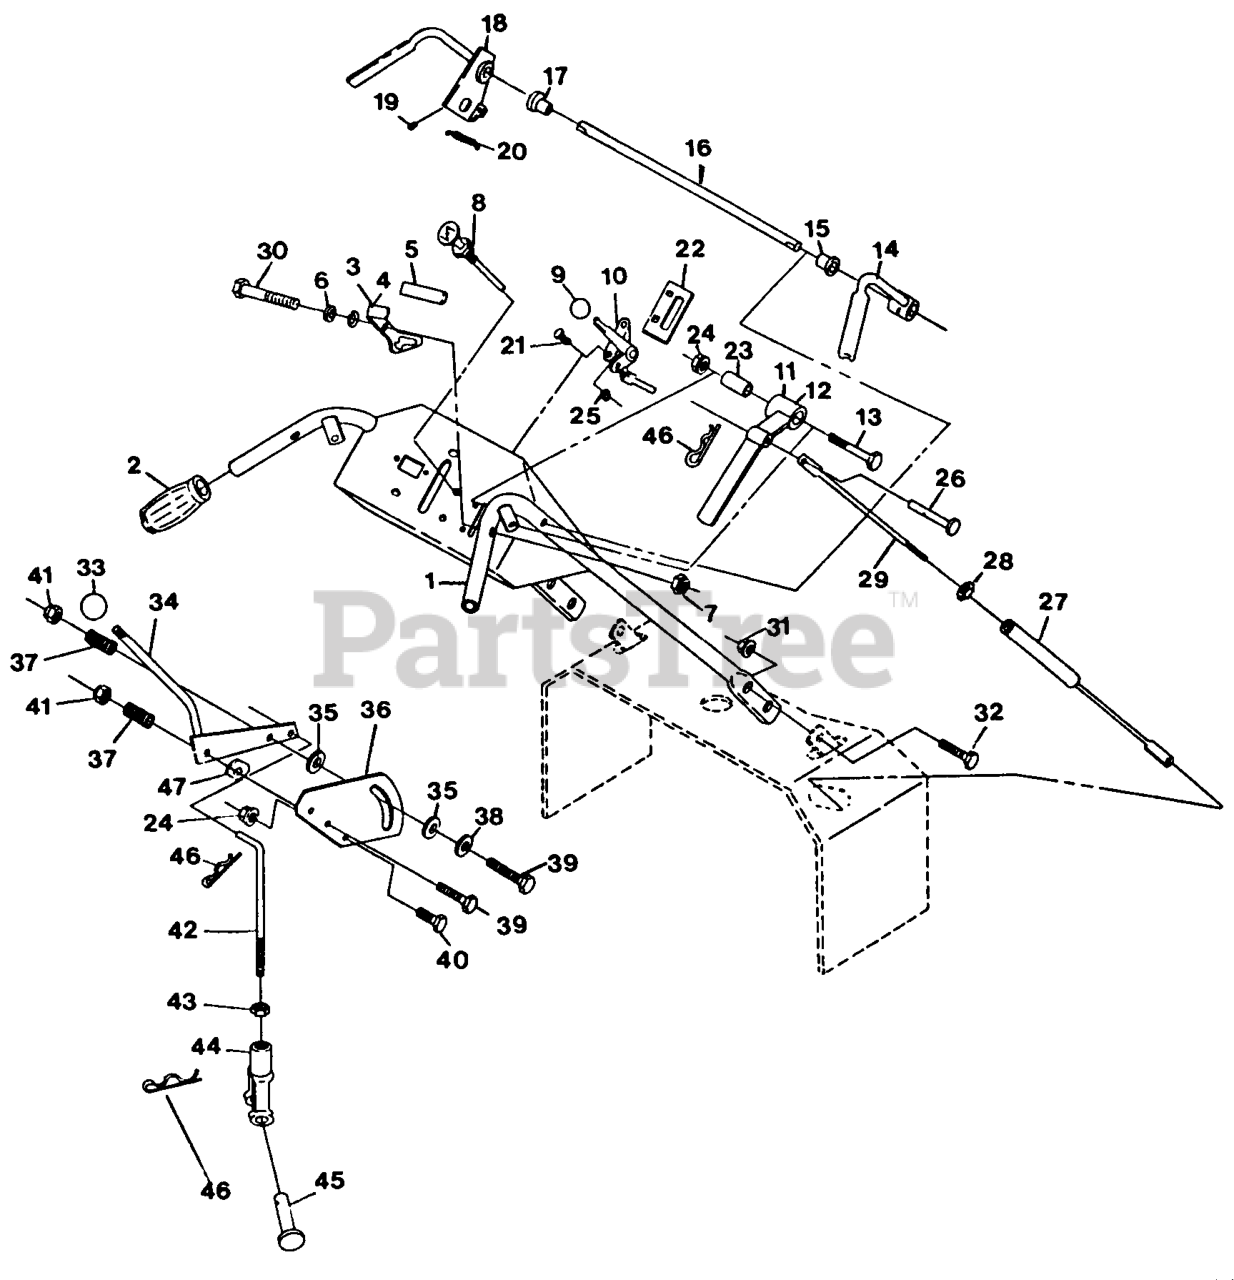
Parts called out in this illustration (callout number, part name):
5	GRIP-LATCH
6	WASHER-SPRING
8	CONTROL-CHOKE
9	KNOB-BALL
15	BUSHING-NYLON
16	ROD,CONNECTING
17	BUSHING,FLANGED
19	SCREW-SET
20	SPRING-EXTENSION
21	BOLT-CARR
23	BUSHING-LEVER, DRIVE
26	PIN - CLEVIS PLTD
33	KNOB-BALL
36	PLATE-LEVER, SHIFTER
38	WASHER-FRICTION
42	ROD,SPEED CONTROL
44	YOKE-ADJUSTABLE
45	PIN-CLEVIS
46	PIN-COTTER
